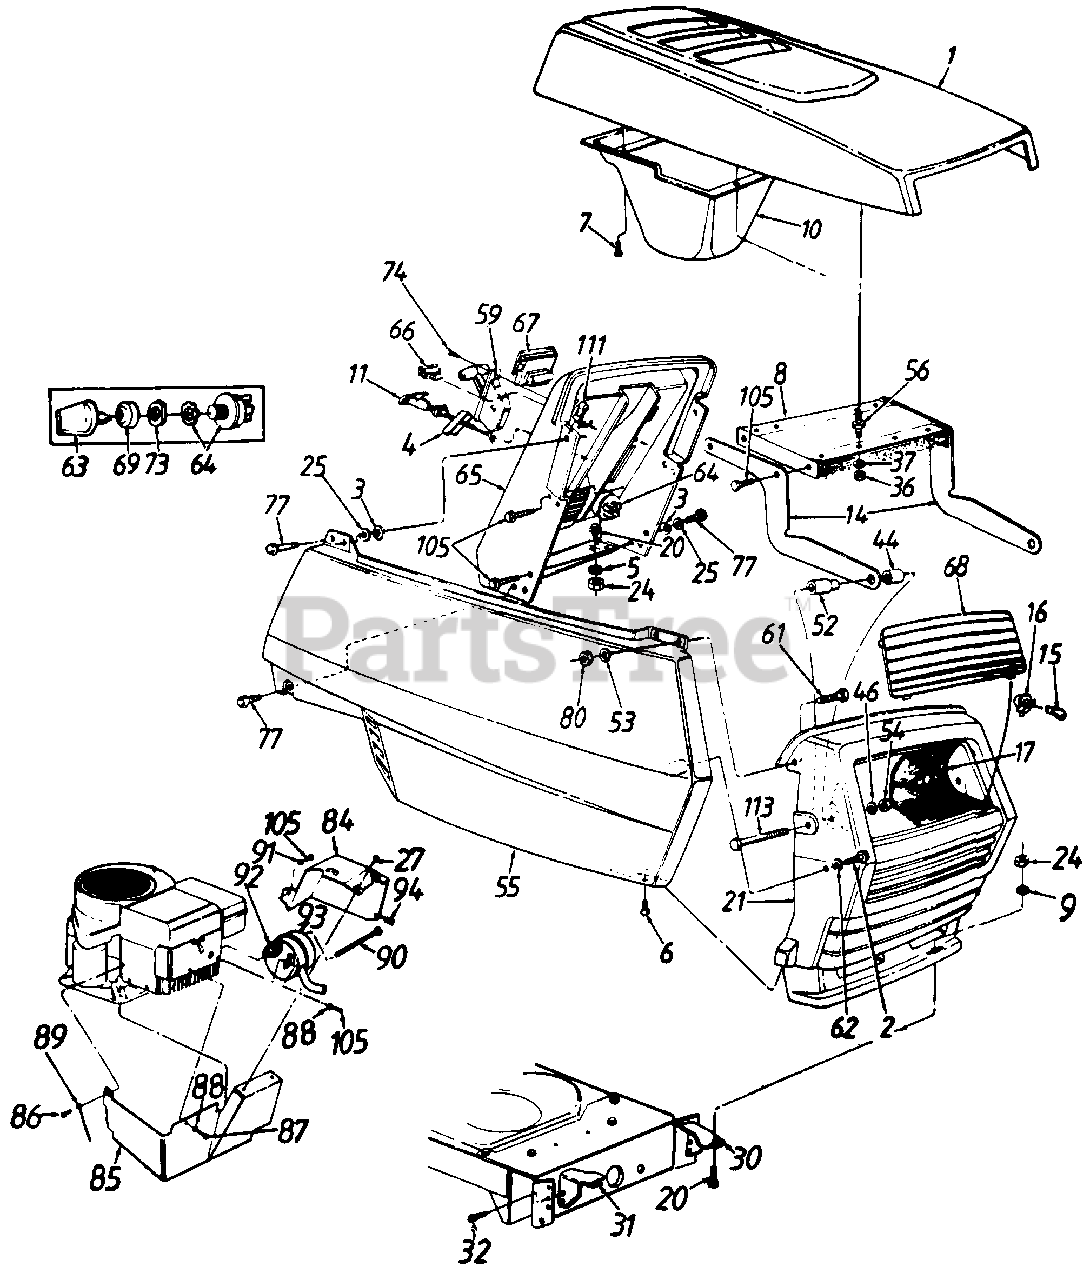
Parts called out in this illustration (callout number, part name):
3	Bolt Retainer 1/4" I.D.
4	Retainer Clip
5	Fl-Wash. .34" I.D. x .68"
6	Truss Mach. B-Tap Scr. #10 x .5" Lg.
7	Hex Wash Hd. AB-Tap Scr. #8 x .5" Lg.
11	Choke Control 29" Lg.
14	Hood Hinge
15	Lamp
16	Twist Lock-Lamp Socket
17	Reflector-Headlight
20	Hex Bolt 5/16-18.75" Lg.
21	Grille
24	Hex Nut 5/16-18 Thd.
25	Fl- Wash. 1/4" I.D. x .93" O.D.
27	Hex B-Tap Scr. #10 x .38" Lg.
30	Grille Mount Brk't.-L.H.
31	Grille Mount Brk't -R.H.
32	Hex Wash. Hd. AB-Tap Scr. 5/16 x .75" Lg.
36	Hex Nut 1/4-20 Thd.
37	Bell-Wash. .265" I.D. x .75"
44	Spacer .33" I.D. x .625" O.D.
46	Fl-Wash, .328" I.D. x .68" O.D.
52	Shld. Spacer .33" I.D.
53	Fl-Wash. .2281" I.D. x .5" O.D
54	Hex Cent. L-Nut 5/16-18 Thd.
55	Side Cover-R.H.
56	Double Ended Stud 1/4-20 Thd.
61	Hex Bolt 1/4-20 x .62" Lg.
62	Fl-Wash. .281" I.D. x .62" Lg.
64	Ignition Switch
65	Dash Panel
66	Light Switch
67	Ammeter
68	Lens
69	Ignition Switch Cap
73	Ignition Switch Nut
74	Truss Mach. AB-Tap Scr. #10 x .5" Lg.
77	Hex Wash. Hd. Tap Scr. 1/4 x .75" Lg.
80	Hex L-Nut 1/4-20 Thd.
84	Muffler Heat Shield-L.H.
85	Muffler Heat Shield-R.H.
86	Pan Hd. Mach. Scr. 5/16-18 x .75" Lg.
87	Hex Bolt 1/4-20 x 3/8" Lg.
88	Spr. Wash. .265" I.D.
90	Shld. Bolt 7/16" Dia. x 3-5/8" Lg.
91	L-Wash. 1/4" I.D.
92	Gasket
93	Muffler
94	Speed Nut #10-24 Thd.
105	Hex Tap Scr. 1/4-20 x .5" Lg.
111	Speed Nut 1/4-20 Thd.
113	Hex Bolt 5/16-18 x 2.75"
